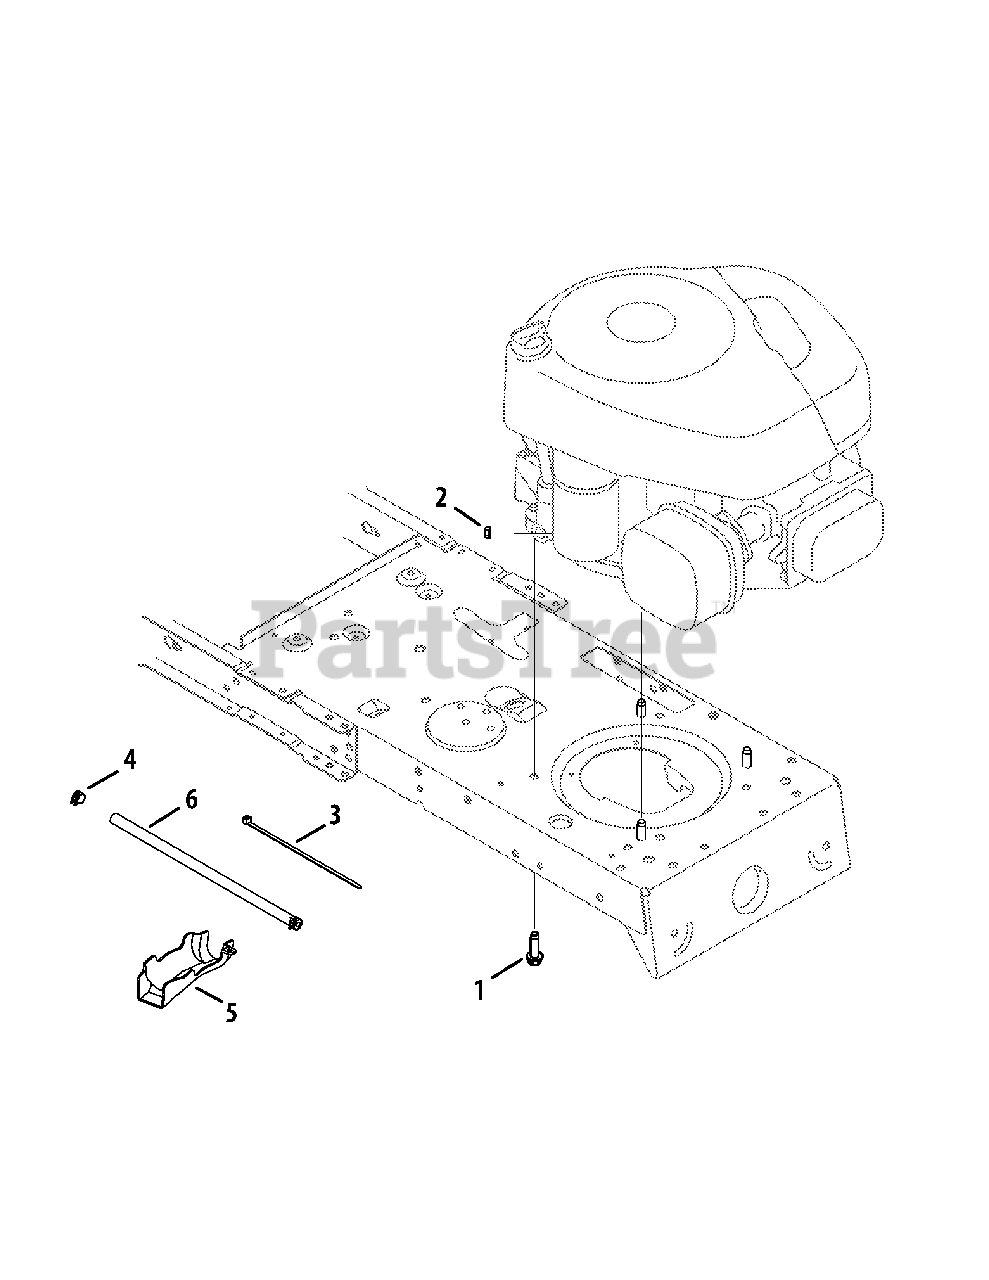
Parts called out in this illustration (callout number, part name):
1	Screw, 3/8-16 x 1.0
2	Sems Nut, 1/4-20
3	Cable Tie
4	Clamp Hose, .490 diameter
5	Oil Drain Sleeve
6	Fuel Hose, Low Permeation
